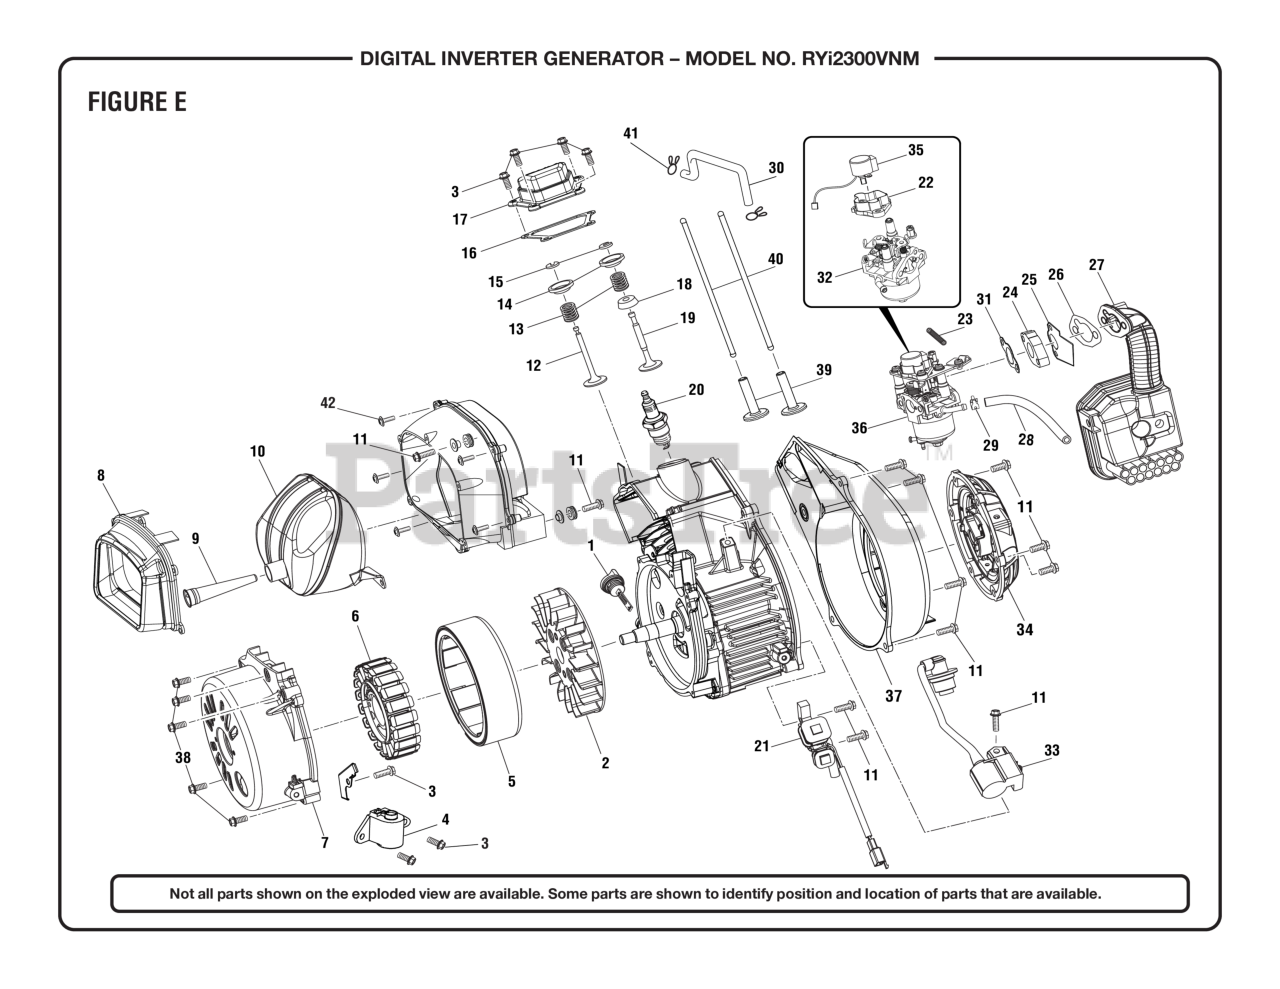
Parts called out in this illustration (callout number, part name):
1	Oil Dipstick
3	Bolt (M6 x 12 mm)
4	Low Oil Sensor
7	Alternator Cover
8	Muffler Heat Shield
9	Spark Arrestor
11	Bolt (M6 x 16 mm)
12	Exhaust Valve
13	Valve Spring
15	Valve Lock Clamp
16	Gasket (Over Head Cover)
17	Over Head Cover
18	Inlet Valve Spring Seat
19	Inlet Valve
20	Spark Plug
21	RPM Sensor
22	Governor Motor Housing
23	Compression Spring
24	Thermal Insulation Seat (Carburator)
25	Paper Gasket
26	Air Box Gasket
27	Air Filter Assembly
28	Fuel Hose (6 mm)
29	Fuel Line Clamp (7/16 in., BM903611)
30	Breather
31	Gasket (Muffler)
32	Carburetor
33	Ignition Coil
34	Engine Recoil
35	Stepper Motor
36	Carburetor Assembly
37	Engine Cover
38	Bolt (M6 x 30 mm)
39	Lifter Valve
40	Pushing Rod
42	Bolt (M3 x 8mm)
